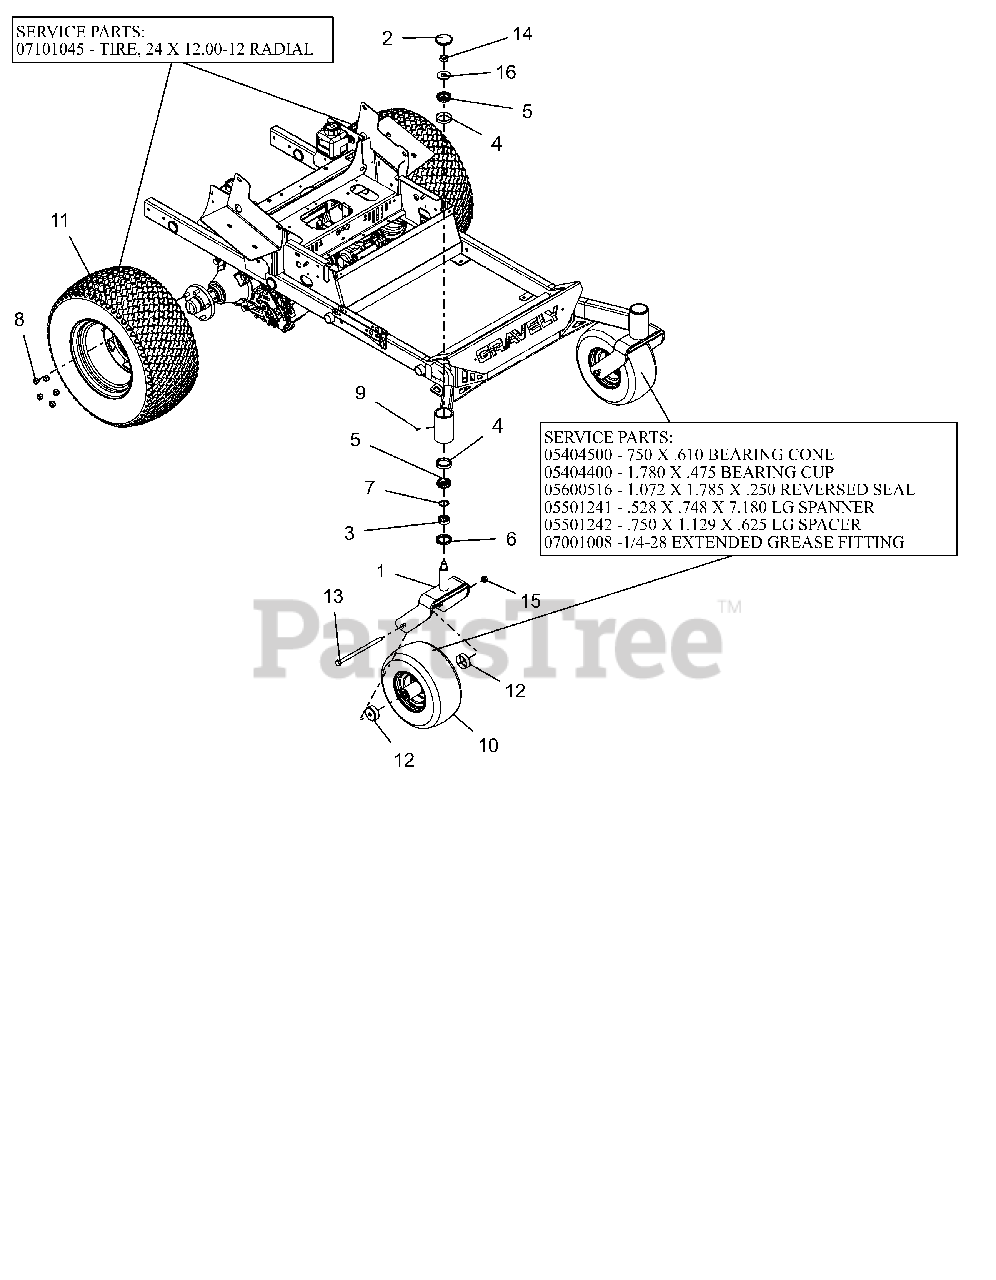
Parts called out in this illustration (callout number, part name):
1	CASTER FORK WMT - RED
2	CAP, DUST
3	SPCR, FRONT CASTER FORK
4	BRG-CUP 2.328X.465
5	BRG-CONE 1.25X.66
6	SEAL, OIL 1.75 X 2.332 X .312
8	WHEEL NUT .500-20 YZ
9	FTG, .25-28 FLUSH MNT GREASE
10	ASM, WHL/TIRE 15X6.00-6 SEMI
10	BRG-CONE .750X.61
10	BRG-CUP 1.781X.475
10	SEAL,1.072X1.785X.250 REVERSED
10	SPANNER, .528X.748X7.18 LG
10	SPACER, .750X1.129X.625 LG
10	GREASE FITTING 1/4-28 EXTENDED
11	ASM,WHL/TIRE 24X12.00-12RADIAL
11	TIRE, 24 X 12.00-12 RADIAL
12	SHIELD, WHEEL BEARING
13	@BLT-HEX .50-13X9.00 GR5 YWZC
14	NUT-JAM TOPLK .75-16 YWZC
15	@NUT-LK-TOP-FLG .50-13 YWZC
16	@WSHR-FL-STL.812X2.00X.148YWZC
